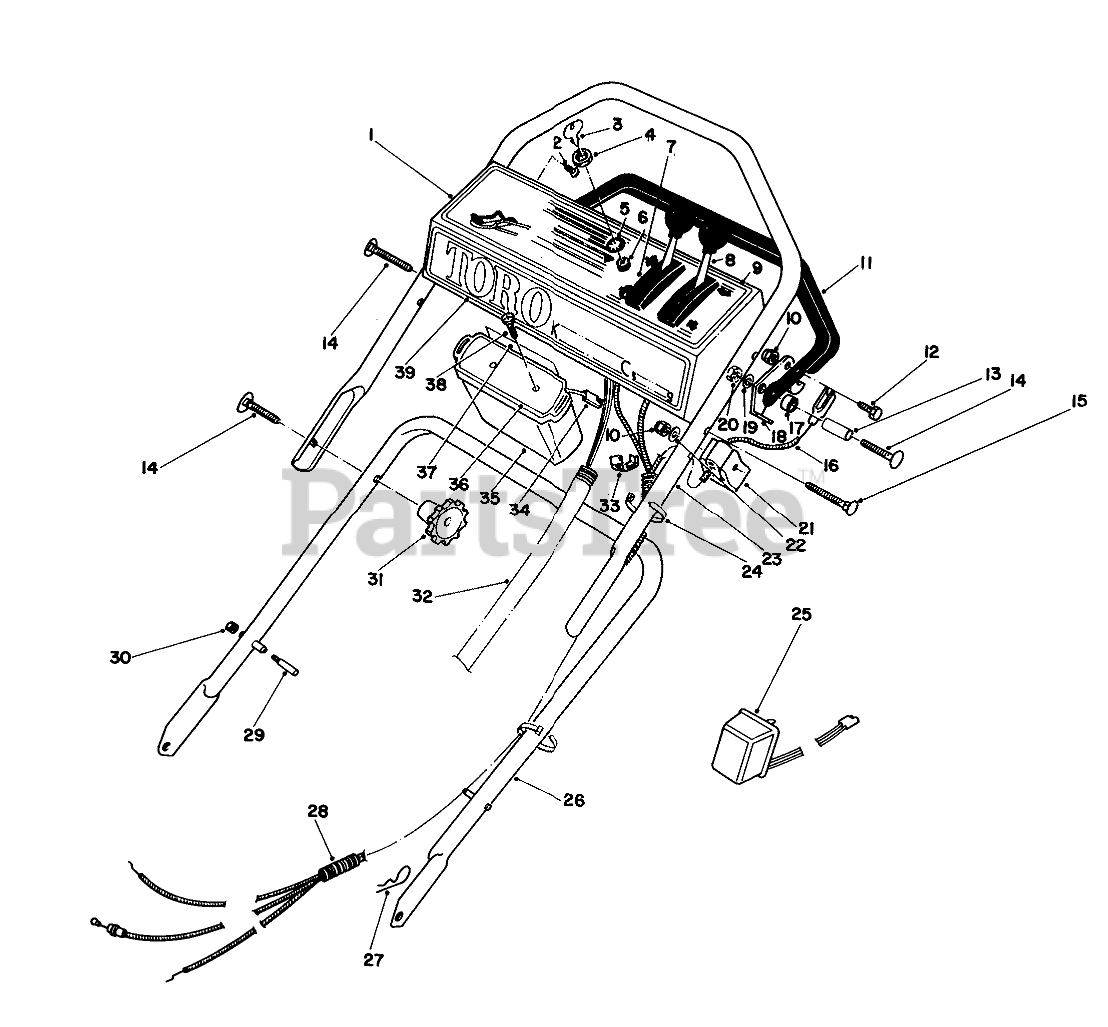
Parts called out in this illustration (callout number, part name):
1	Control Panel (Incl. Ref. #9)
2	SCREW-HWHTF
3	Key
4	NUT-HH
5	WASHER-TOOTH, INTERNAL
6	Switch-Starter (Incl. Ref. #4-5)
7	SERVICE TRACT. CONTROL
8	SERVICE THROTTLE CONTRO
9	INSTRUCTION DECAL
10	NUT-LOCK, NI
11	Bar-Control
12	SCREW-HH
13	Spacer
14	5/16-18 X 2 HNDLE SCREW
15	SCREW-HANDLE
16	BRAKE CABLE-SUZUKI
17	Nylon Spacer
18	Lever-Control
19	WASHER-PLAIN
20	NUT-LOCK, NI
21	SUPPORT-CABLE
22	WASHER-FLAT
23	UPPER HANDLE
24	TIE-CABLE
25	Charger
26	LOWER HANDLE ASSEMBLY
27	PIN-COTTER, HAIR
28	CONT. CABLE COVER
29	HANDLE PIN
30	Nut
32	WIRE HARNESS
33	FITTING-RING
34	LEAD WIRE ASM
35	Battery Case
36	BATTERY COVER
37	Decal
39	Decal-Toro
